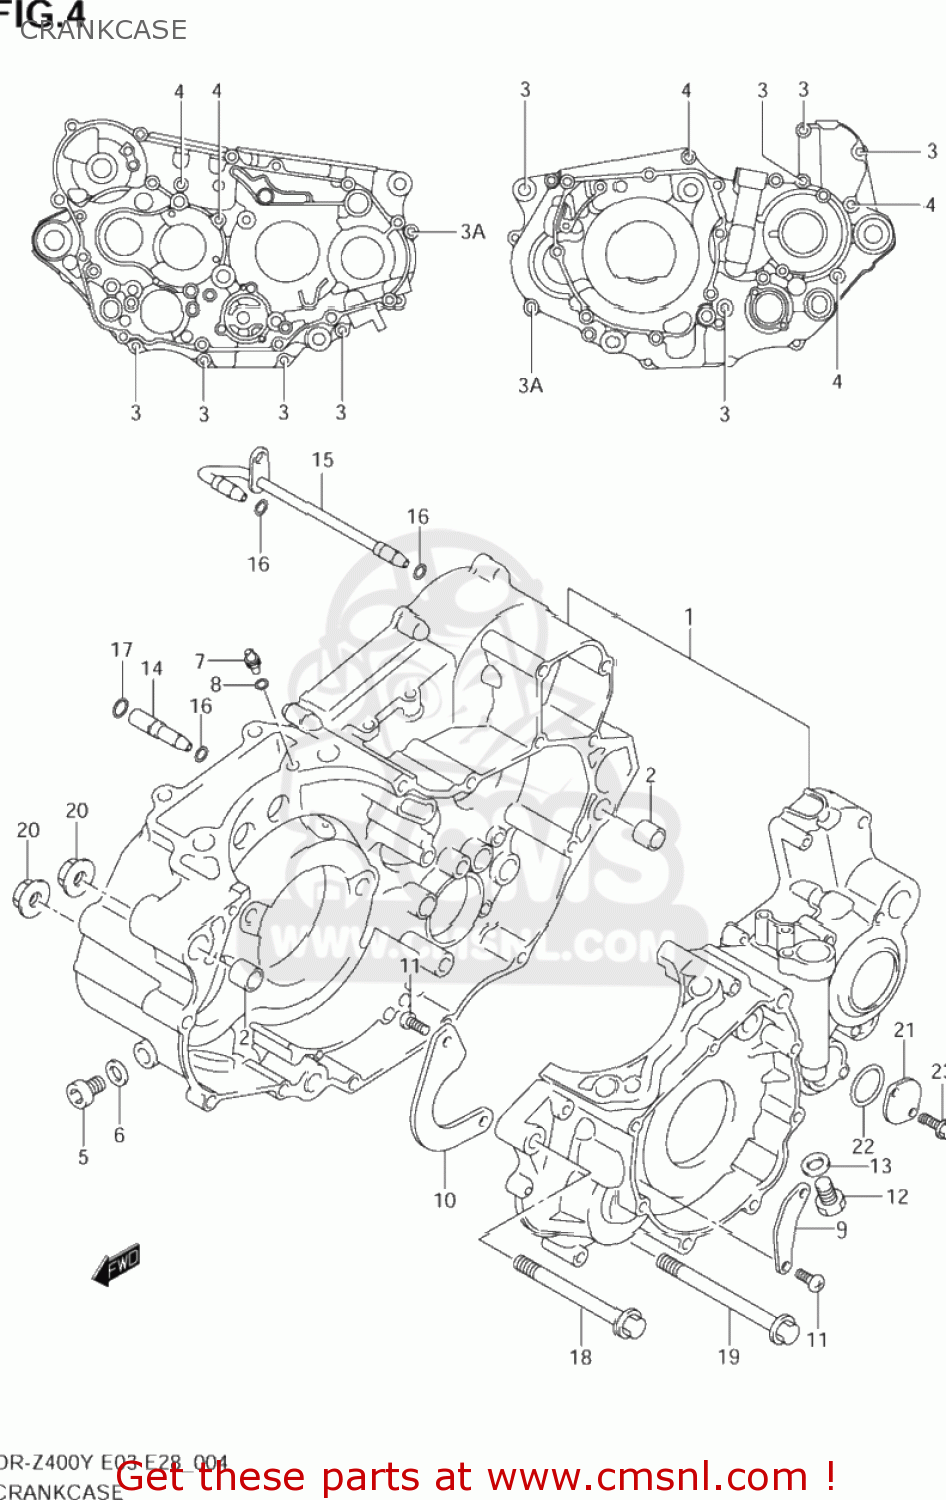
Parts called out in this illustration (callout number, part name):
1	CRANKCASE SET
2	PIN
3	BOLT
3A	BOLT
4	BOLT
5	PLUG(10X10)
6	GASKET(10X14X3.6) (NAS)
7	JET(8)
8	O RING(D:1.2,ID:4)
9	SEPARATOR,CRANKCASE OIL NO.1
10	SEPARATOR,CRANKCASE OIL NO.2
11	SCREW(6X12)
12	PLUG(12X20)
13	GASKET(12.1X16.2X3.7) (NAS)
14	PIPE,OIL INNER NO.1
15	PIPE,T/M OIL INNER NO.2
16	O RING(D:1.9,ID:4.8)
17	O RING(D:1.9,ID:6.8)
18	BOLT(10X100)
19	BOLT(10X115)
20	NUT
21	CAP,GEAR SHIFT CAM PIVOT
22	O RING(D:2.4,ID:26.2)
23	BOLT
